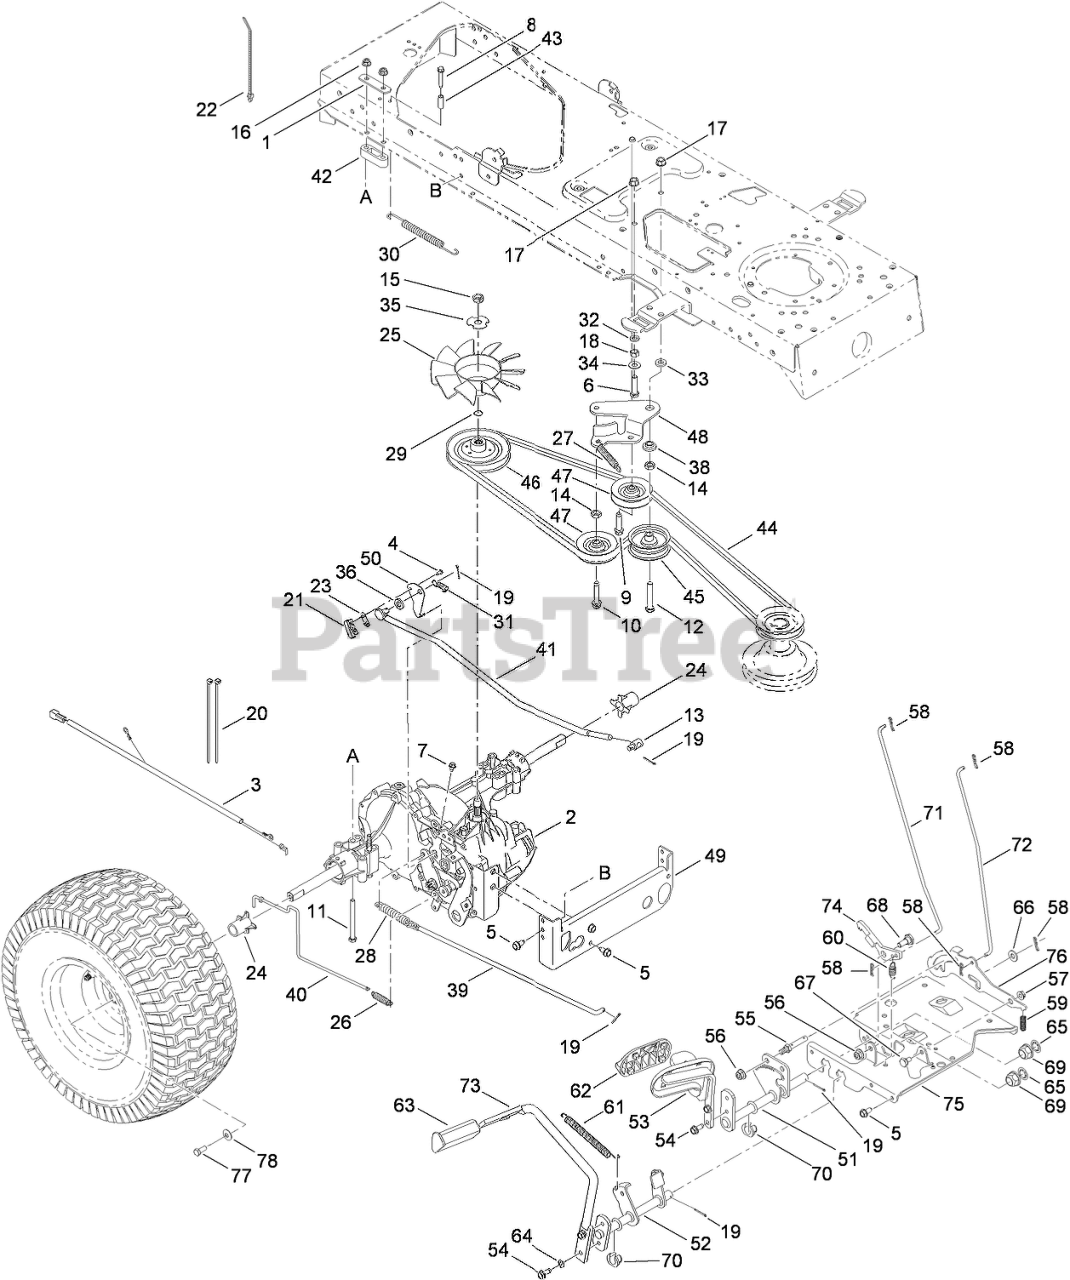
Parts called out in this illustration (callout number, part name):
1	BRACKET-MOUNTING, TRANSMISSION
2	HYDRO TRANSMISSION ASM
3	HARNESS ASM
4	SCREW-HWHTF
5	SCREW-TAP
6	SCREW-HH
7	50 INCH SIDE DISCHARGE DECK ASM
8	SCREW-HWH
9	SCREW-TAP
10	SCREW-TAP
11	SCREW-HH
12	SCREW-HH
13	FERRULE
14	NUT-JAM
15	NUT-JAM
16	NUT-LOCK, FLANGE
17	NUT-LOCK, FLANGE
18	NUT-LOCK, FLANGE
19	PIN-COTTER
20	TIE-CABLE
21	SWITCH-SPRING, SHORT
22	TIE-CABLE
23	PLATE-INSULATOR
24	SLEEVE
26	SPRING-EXTENSION
27	SPRING-EXTENSION
28	SPRING-EXTENSION
29	RING-WIRE
30	SPRING-EXTENSION
31	SPRING-EXTENSION
32	WASHER-LOCK
33	WASHER-FLAT
34	WASHER-FLAT
35	WASHER-LOCK
36	WASHER-FLAT
38	SPACER-SHOULDER
39	ROD-BRAKE
40	ROD-HYDRO
41	ROD-CONTROL
42	SPACER-TRANSAXLE
43	SPACER
44	BELT-V
45	PULLEY-IDLER, FLAT
46	PULLEY-INPUT
47	PULLEY-IDLER, Y TYPE
48	BRACKET-IDLER, CENTER DOUBLE
49	BRACKET-TORQ, TRANSMISSION
50	BRACKET-ACTUATOR
51	CONTROL ASM
52	SPEED CONTROL ASM
53	CONTROL PEDAL ASM
54	SCREW-HWH
56	NUT-LOCK, FLANGE
57	NUT-LOCK, FLANGE
58	PIN-COTTER
59	SPRING
60	SPRING-EXTENSION
61	SPRING-EXTENSION
62	PAD-PEDAL
63	PAD-BRAKE
64	WASHER-LOCK
65	WASHER-FLAT
66	Washer-Flat
67	BOLT-SHOULDER
68	BOLT-SHOULDER
69	BEARING-FLANGE
70	BEARING-FLANGE, HEX (SPLIT)
71	ROD-BRAKE, LOCK
72	ROD-CONTROL, CRUISE
73	PEDAL-BRAKE
74	LATCH-CRUISE
75	BRACKET-SUPPORT, STEERING
76	BRACKET-LOCKOUT
77	SCREW-HH
78	WASHER-BELL
